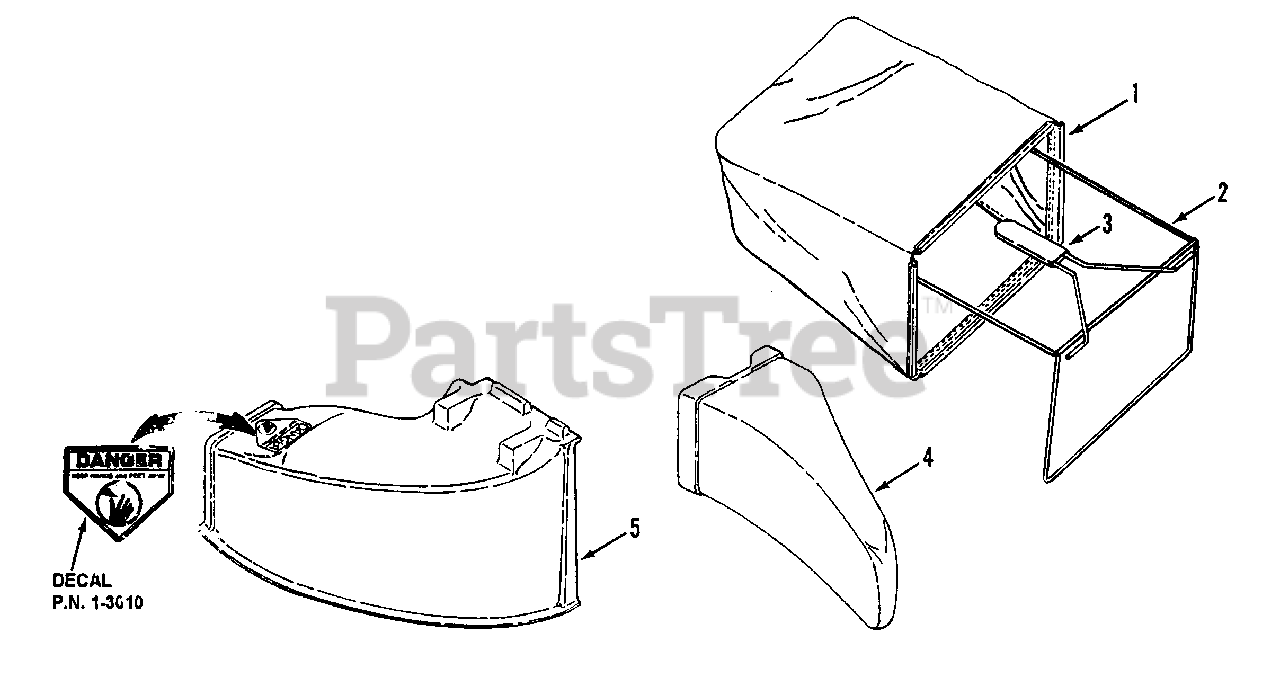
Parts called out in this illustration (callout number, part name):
1	Grass Catcher
2	ASSEMBLY, Catcher Frame
3	Grip
4	Mulching Plug
5	Side Discharge Chute
